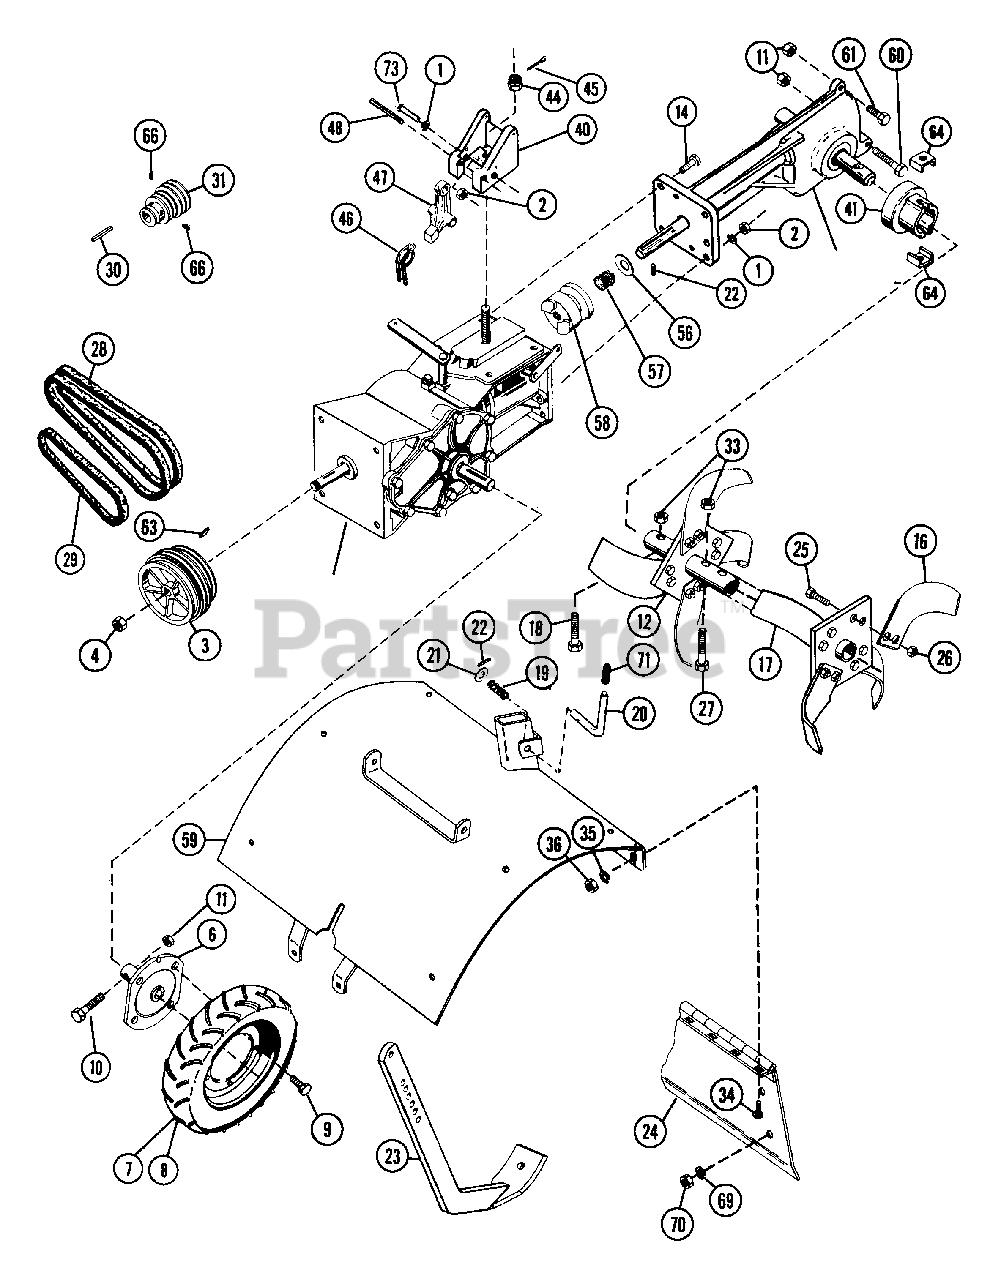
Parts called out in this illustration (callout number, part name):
1	WSHR-LK .375X.115 HVY PL
2	NUT-HEX .375-16
3	DRIVE SHEAVE
4	NUT-LK-CTR .75-16 PL
5	KEY-FTHR .25X1.875X.25 SAE
6	WHEEL HUB
7	R H TIRE AND RIM ASSY
8	L H TIRE AND RIM ASSY
9	SCR-TAP .500-20X.62 HH PL
10	BLT-HEX .31-18X2.00 PL GR2
11	NUT-LK .312-18 GR A PL
12	INNER TINE HUB
14	BLT-HEX .38-16X1.75 PL GR2
15	NUT-LK .375-16 PL
16	R KNIFE TINE
17	L KNIFE TINE
18	BLT-HEX .38-16X2.75 GR8
19	SG-COMP .045X.50X1.187
20	DEPTH REGULATING PIN
21	WSHR-FL-STL .38X.875X.083 PL
22	PIN-ROLL .125X1.00
23	DEPTH SHOE
24	TAILBOARD
25	BLT-HEX .44-14X1.00 GR5
26	NUT-LK-TOP .437-14 GR C PL
27	BLT-HEX .38-16X2.00 GR8
28	V-BELT, SAE 380-RAW EDGE (SET)
29	V-BELT, 3L-COGGED
30	KEY-SQ .25 X 1.25 X .25 SAE
31	ENGINE SHEAVE
33	NUT-LK TOP .375-16 GR C YWZC
34	BLT-RDHDSQSHNK .31-18X.50 YZ
35	WSHR-LK .313X.093 MED HICLR
36	NUT-HEX .312-18
40	HANDLEBAR BRACKET
41	DUST CAP
44	NUT-SL .50-13
45	PIN-COTR .12X1.0 PL
46	SG-TORS .109X.88X2.25
48	PIN-ROLL .313X2.00
56	WSHR-FL-STL .755X1.375X.125
57	SG-COMP .080X.97X2.18 WLD14
58	TILLER JAW CLUTCH
59	TINE HOOD WITH DECALS
60	BLT-HEX .31-18X3.50 PL GR2
61	BLT-HEX .31-18X1.25 PL GR2
65	BLT-HEX .38-16X2.00 PL GR2
66	SCR-SET .32-18X.38 SKHCUPNL OH
73	BLT-HEX .38-16X1.00 PL
